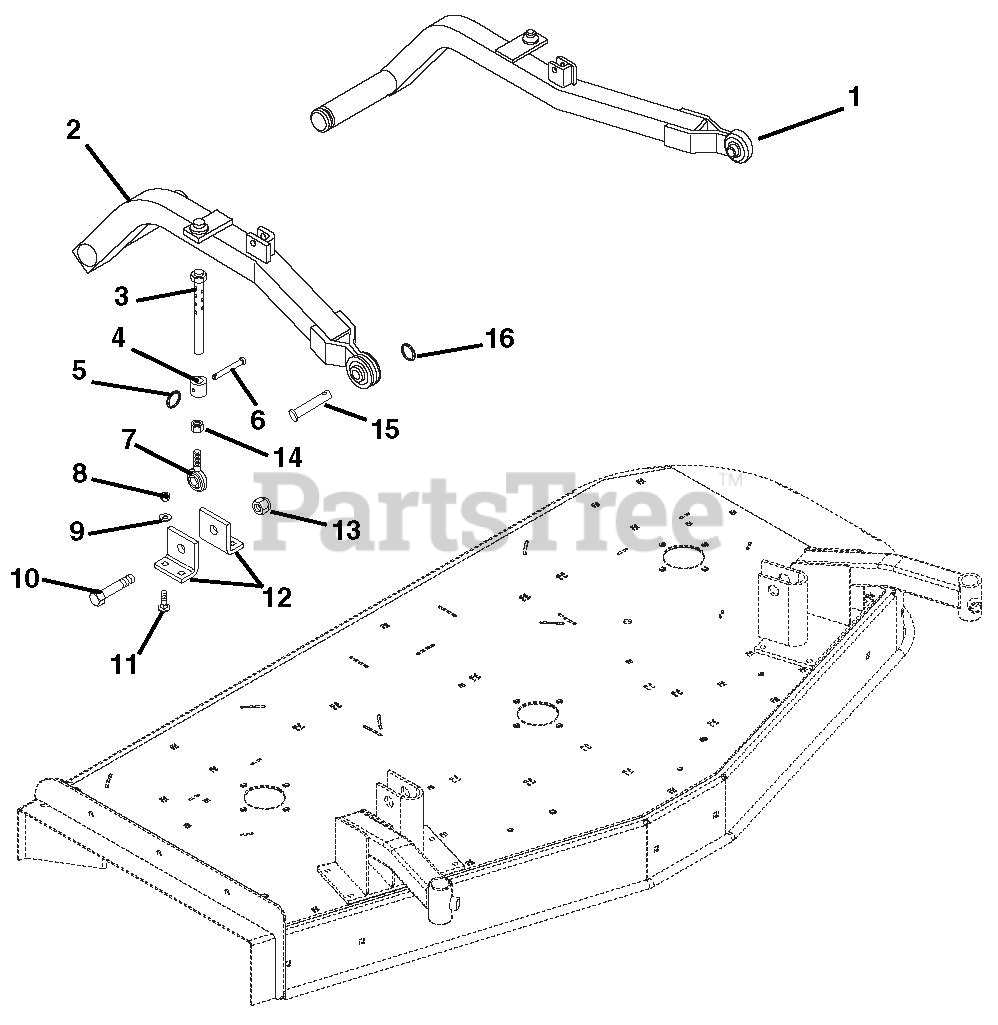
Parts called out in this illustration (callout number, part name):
1	WLDMT,MOWER MTG ARM L.H.
2	WLDMT,MWR ARM (R.H.)
3	WLDMT,HEIGHT ADJUSTMENT
4	SPACER .765X1.25X.910 ST
5	PIN-KLIK 1.000X.188X1.25 YWZC
6	PIN-CLEV .31 X 2.62 GR5 YWZC
7	ROD,END
8	NUT-LK-NYL .38-16 YWZC
9	WSHR-FL-STL.406X.812X.065 YWZ
10	BLT-HEX .75-10X3.50 GR5 YWZC
11	BLT-RDHDSQNK .38-16X1.25 G5YZ
12	BRKT,DECK SUPPORT REAR
13	NUT-LK-NYL .75-10 YWZC
14	NUT-LK-CTR-JAM .50-13 YWZC(ND)
15	PIN-CLEV .875X3.00 YWZC
16	RG-RTNG-EXT 2.240 X .180 YWZC
